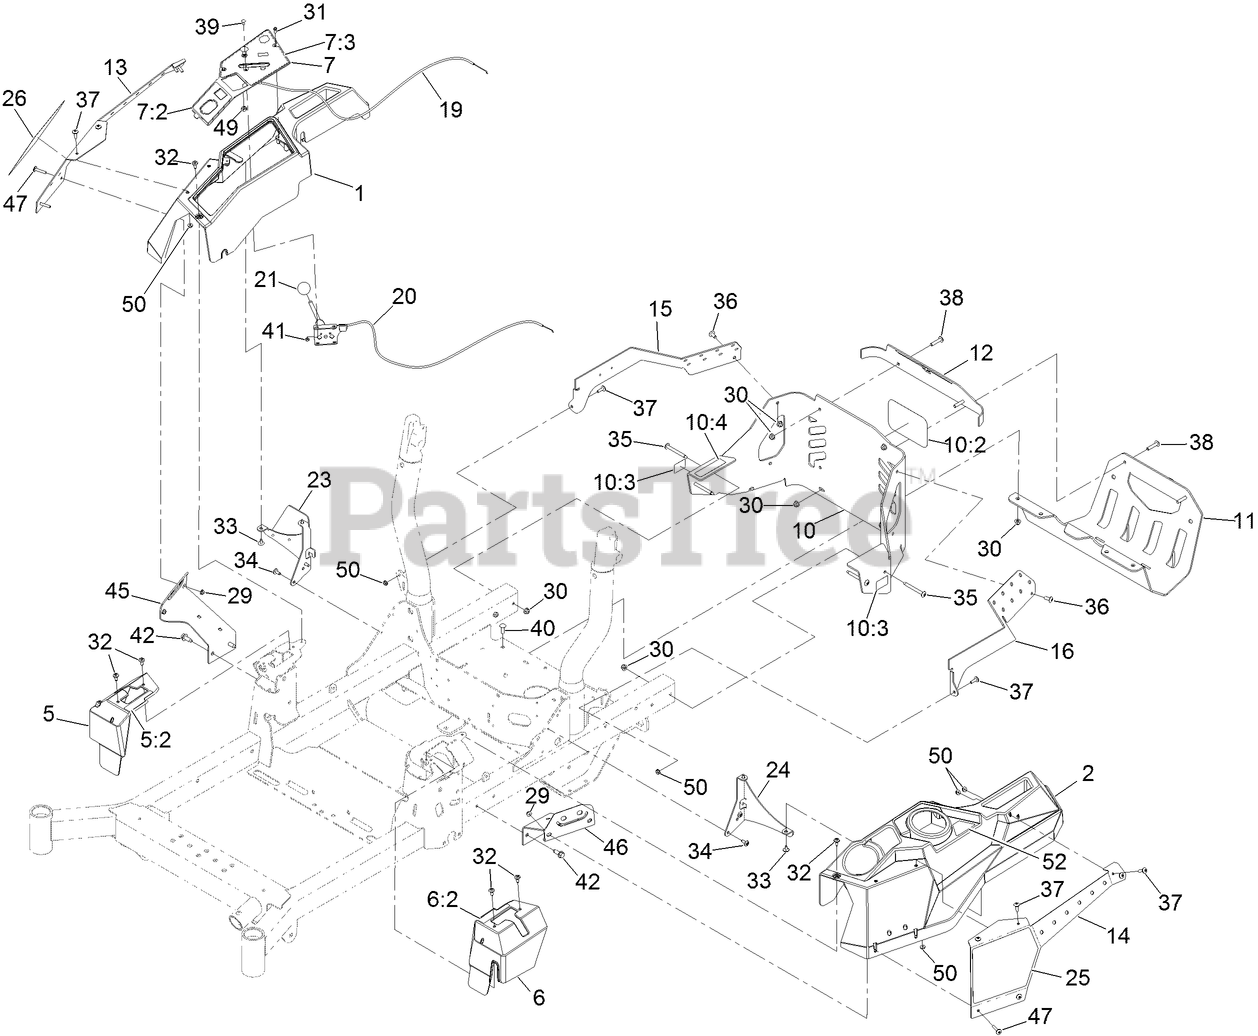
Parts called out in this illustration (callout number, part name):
1	CONSOLE-RH
2	CONSOLE-LH
5	COVER-CONTROL, MOTION (RH)
5:2	DECAL-CONTROL, MOTION (RH)
6	COVER-CONTROL, MOTION (LH)
6:2	DECAL-CONTROL, MOTION (LH)
7	CONTROL PANEL ASM
7:2	DECAL-PANEL, CONTROL
7:3	DECAL-PANEL, CONTROL
10	REAR GUARD ASM
10:2	DECAL
10:3	DECAL-WARNING
10:4	DECAL-ARRESTOR, SPARK
11	GUARD-MUFFLER
12	TRIM-UPPER REAR
13	COVER,POD RH
14	COVER [BLACK]
15	BRACKET-GUARD, RH [RED]
16	BRACKET-GUARD, LH
19	CABLE-CONTROL, CHOKE
20	CABLE-CONTROL, THROTTLE
21	KNOB-BALL
23	SUPPORT-CONSOLE, RH
24	BRACKET-CONSOLE, LH
25	DECAL - HDX
26	DECAL - HDX
29	NUT-HF
30	NUT-HF, NI
31	SCREW-HWH
32	SCREW-SHOULDER
33	SCREW-TORX
34	SCREW-TORX
35	SCREW-TORX
36	SCREW-TORX
37	SCREW-TRUSS
38	SCREW-TORX
39	BOLT-CARR
40	SCREW-CARR
41	NUT-LOCK, NI
42	SCREW-FORMING, THREAD
45	BRACKET-SUPPORT, POD (RH)
46	BRACKET-SUPPORT, POD (LH)
47	SCREW-TRUSS
49	NUT-HJ
50	NUT-KEPS
52	DECAL-FILL, FUEL
